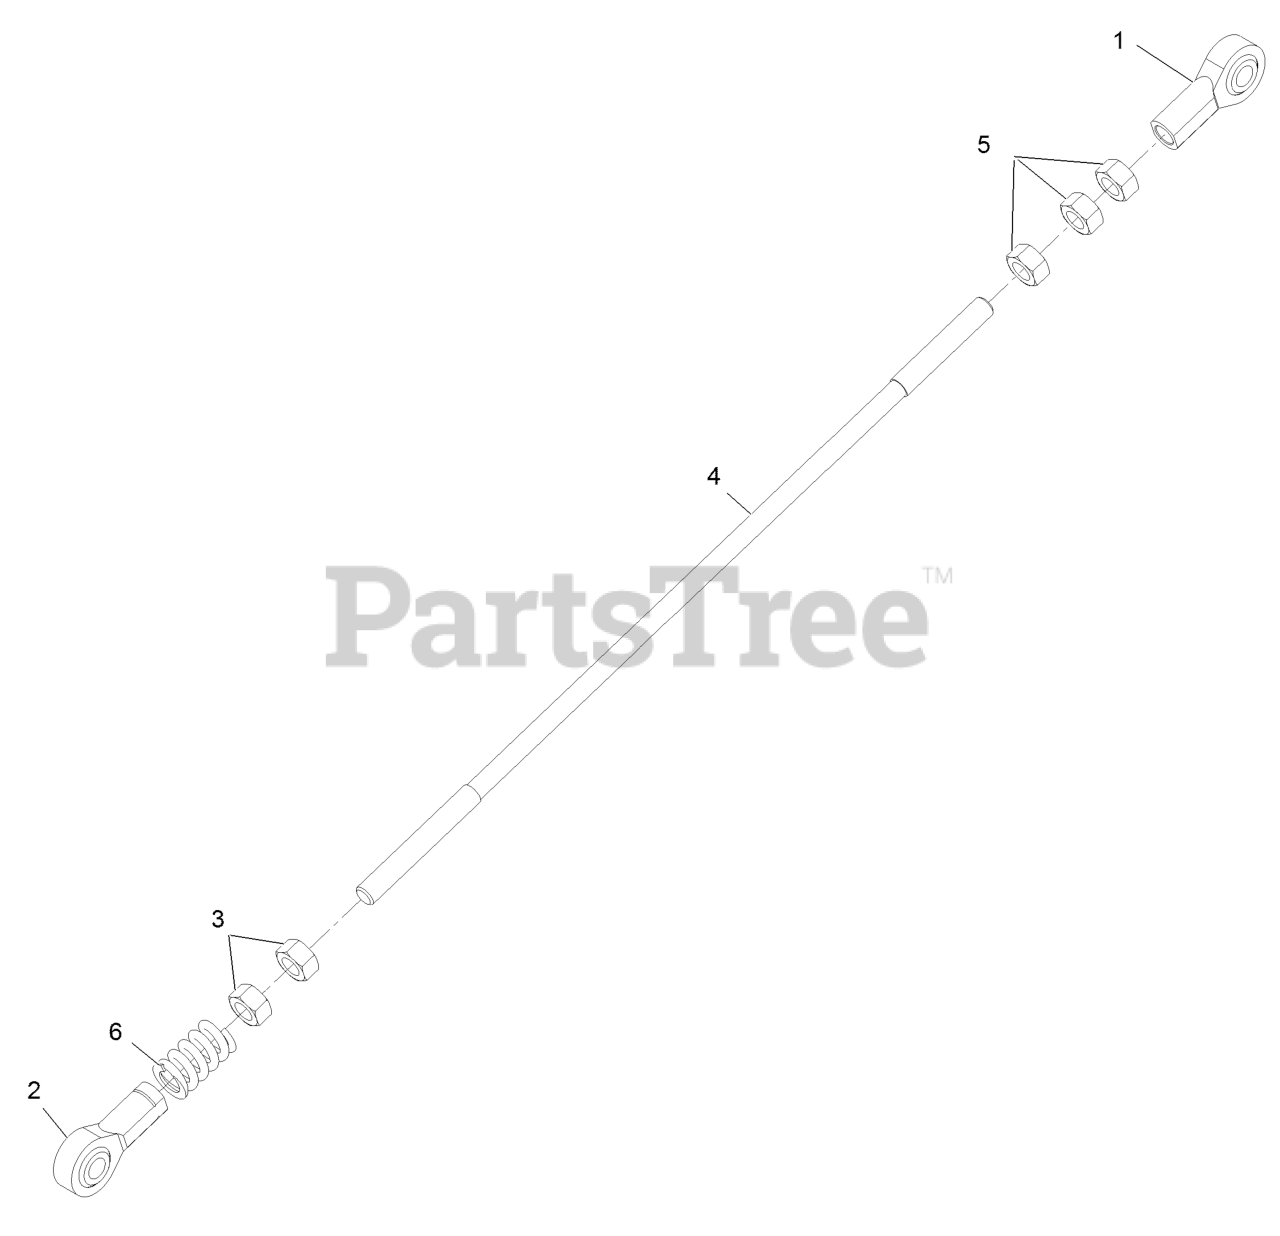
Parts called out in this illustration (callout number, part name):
1	BALLJOINT-RH
2	BALLJOINT-LH
4	LINK,XP HYDRO CONNECT RH
5	NUT-HEX
6	SPRING-COMPRESSION
